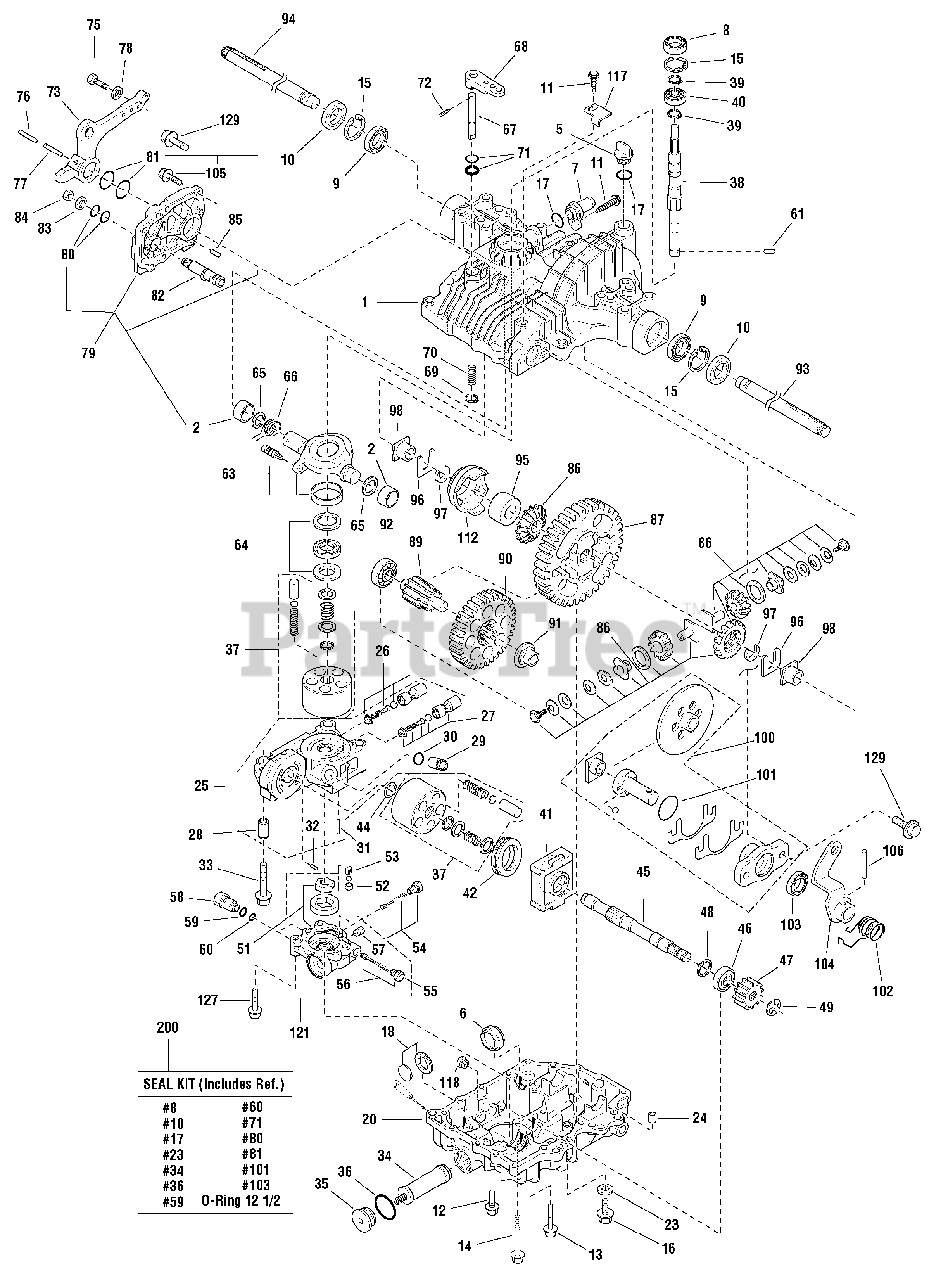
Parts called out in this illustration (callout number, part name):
1	CASE SET, (K71J Only, See Ref. No. 20 for K71G)
2	BEARING, 28 x 15
5	CAP, Oil, 20
10	SEAL
11	SCREW, Tapping, 8 x 25
12	*SCREW, Tapping
14	BOLT, 8 x 75"
16	BOLT, 10 x 12
17	PACKING, P18
18	MAGNET, Complete
20	CASE SET (B)
23	WASHER, Seal 10
24	PIPE, 13 x 11.3
25	*CENTER CASE, Complete
26	*VALVE, (A-1 SET)
27	*VALVE, (A-2 SET)
28	KNOCK PIN, 15.5 x 30
29	PLUG, 16 x 25
32	PIN, 3 x 9.8
33	BOLT, 10 x 75
34	FILTER
37	*CYLINDER BLOCK, Complete
40	BEARING, 6303
41	*HOUSING
44	WASHER, 18 x 31 x 1
45	*SHAFT MOTOR
46	BEARING 6004 SH2 U
47	*MOTOR GEAR
49	RING, E15
51	*PUMP CASE, Complete
52	*3RD CHECK, Complete
53	*HOLDER, (SEAT)
54	*VALVE, (IMP COMPLETE)
55	*PLUG
56	*VALVE, (Charge Complete)
57	PLUG, PT 1/8
59	PACKING, P16
60	PACKING, 6.1
61	PIN, 3.2 x 21
63	*SWASH PLATE, Complete
64	*BEARING, Complete
65	*WASHER
66	*SPRING (N/C)
67	*SHAFT (BYPASS)
68	*LEVER (BYPASS)
71	O-RING, 1A P10A
72	PIN, 3.0A*20
73	CONTROL LEVER
76	PIN, 6.0A x 50
77	PIN, 3.5A x 50
79	SIDE COVER SET
80	PACKING, P14
81	PACKING, P28
82	*FULCRUM, (ECCENT)
86	DIFF GEAR KIT
87	*FINAL GEAR
89	*SHAFT, (F PINION)
90	*REDUCTION GEAR
93	AXLE SHAFT, Left
94	*AXLE SHAFT, Right
95	*COLLAR, (Diff. Lock)
96	THRUST WASHER
98	*BUSHING
102	SP, (RETURN)
103	SEAL, TC173007
104	*ARM, (BRAKE)
106	PIN, 6.0A x 4.0
112	*SLIDER, (Diff. Lock)
117	*STOPPER, Brake
118	*BORE PLUG
121	PUMP CASE S/A
127	BOLT, 8 x 45
129	BOLT, 8 x 25
200	SEAL KIT, K71H, E, J, L
201	*KIT, Repair
